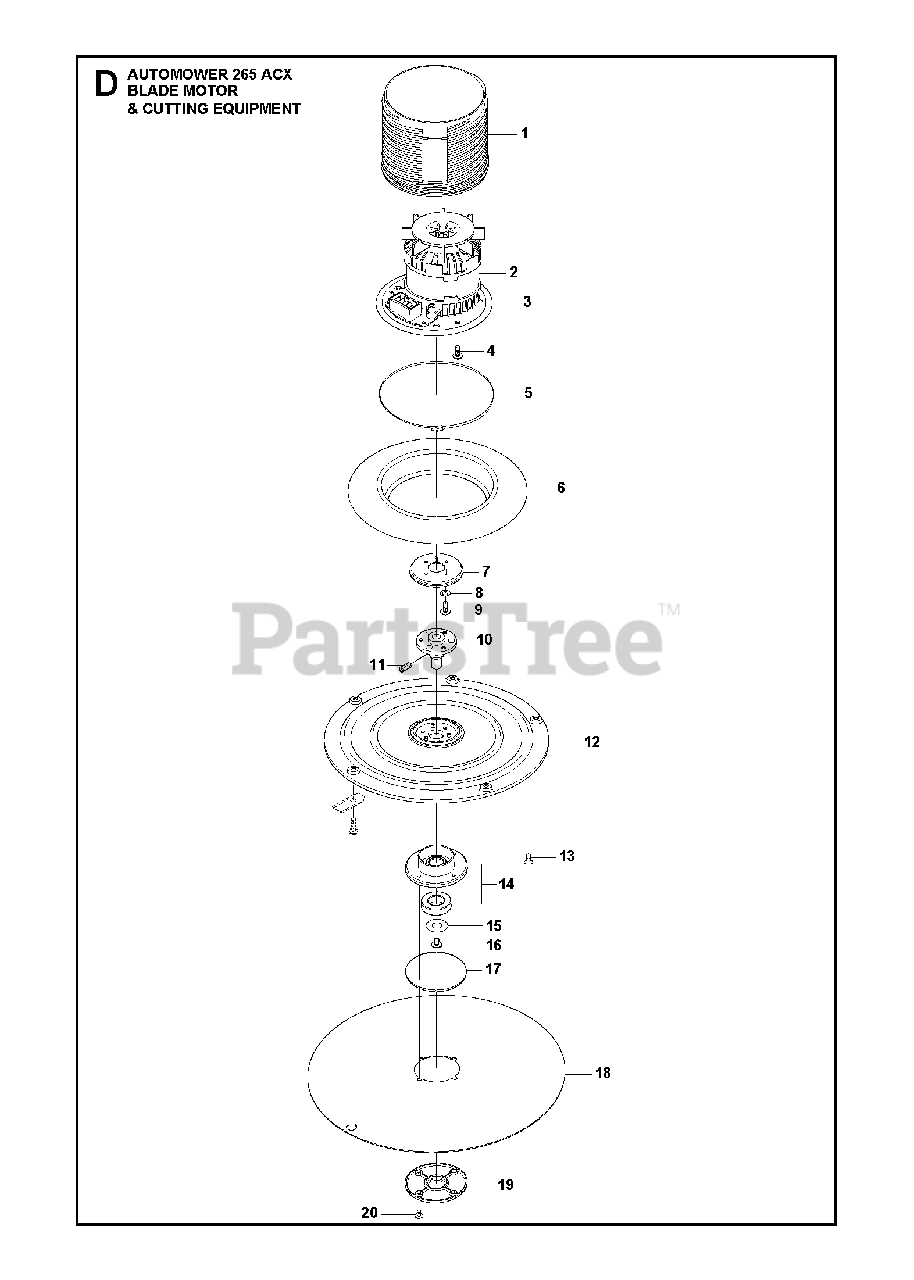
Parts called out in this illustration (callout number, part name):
1	MOTOR BOWL CUTTING MOTOR
4	SCREW 14MM
8	LOCKWASHER
13	SCREW
16	SCREW
